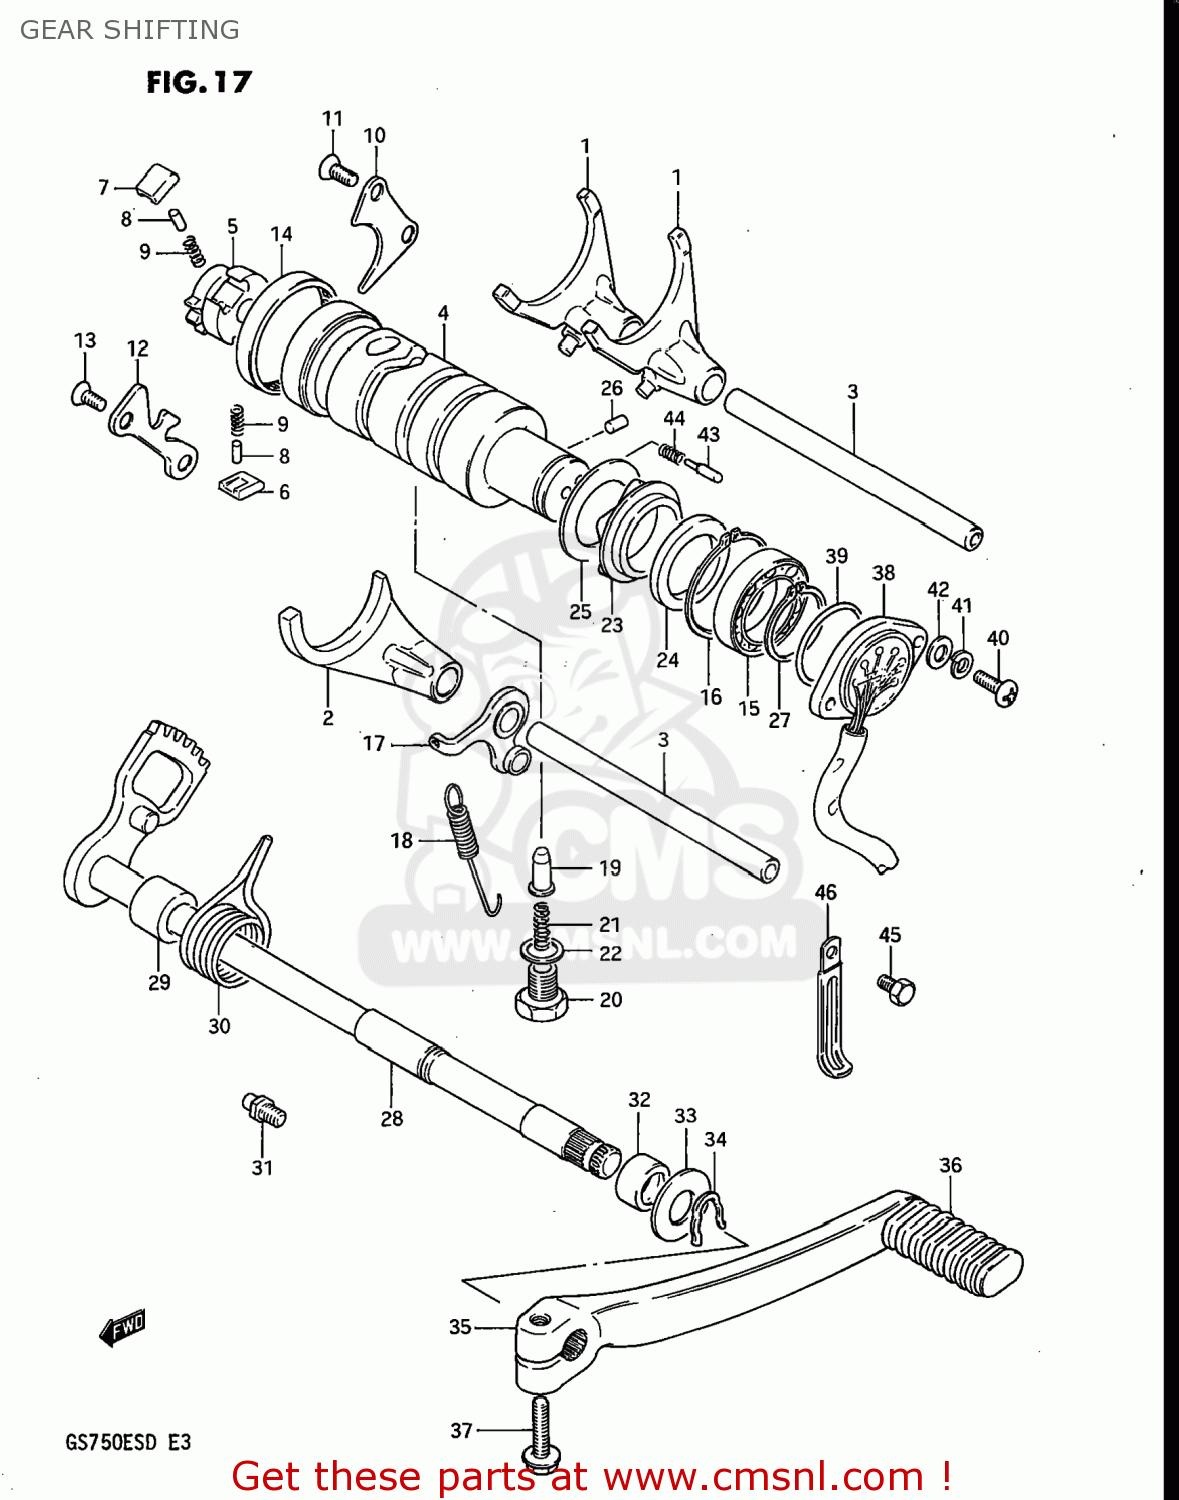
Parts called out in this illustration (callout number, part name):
1	FORK,GEAR SHIFT NO.1
2	FORK,GEAR SHIFT NO.2
3	SHAFT,GEAR SHIFT FORK
4	CAM,GEAR SHIFT
5	RETAINER,GEAR SHIFT CAM
6	PAWL,GEAR SHIFT NO.1
7	PAWL,GEAR SHIFT NO.2
8	PIN(5X8)
9	SPRING
10	LIFTER,GEAR SHIFT PAWL
11	SCREW
12	GUIDE,GEAR SHIFT CAM
13	SCREW
14	BEARING(43X49X12)
15	BALL BEARING
16	CIRCLIP,42MM
17	STOPPER,GEAR SHIFTING
18	SPRING
19	STOPPER,GEAR SHIFTING
20	HOLDER,GEAR SHIFT CAM STOP SPR
21	SPRING
22	GASKET(14X19.2X2) (NAS)
23	PLATE,STOPPER
24	WASHER
25	WASHER,LOCK
26	PIN 4X6
27	CIRCLIP,25MM
28	SHAFT,GEAR SHIFT
29	SPACER(12X20X15.3)
30	SPRING
31	STOPPER,GEAR SHIFT CAM
32	OIL SEAL
33	WASHER (12.5X27X1.6)
34	SPRING,RETAINER
35	LEVER ASSEMBLY,GEAR SHIFTING
36	RUBBER,PEDAL
37	BOLT
38	TERMINAL BASE,NEUTRAL
39	O RING(D:2.4,ID:36.5)
40	SCREW
41	LOCK WASHER
42	WASHER
43	PIN(5X15.5)
44	SPRING
45	BOLT
46	CLAMP
